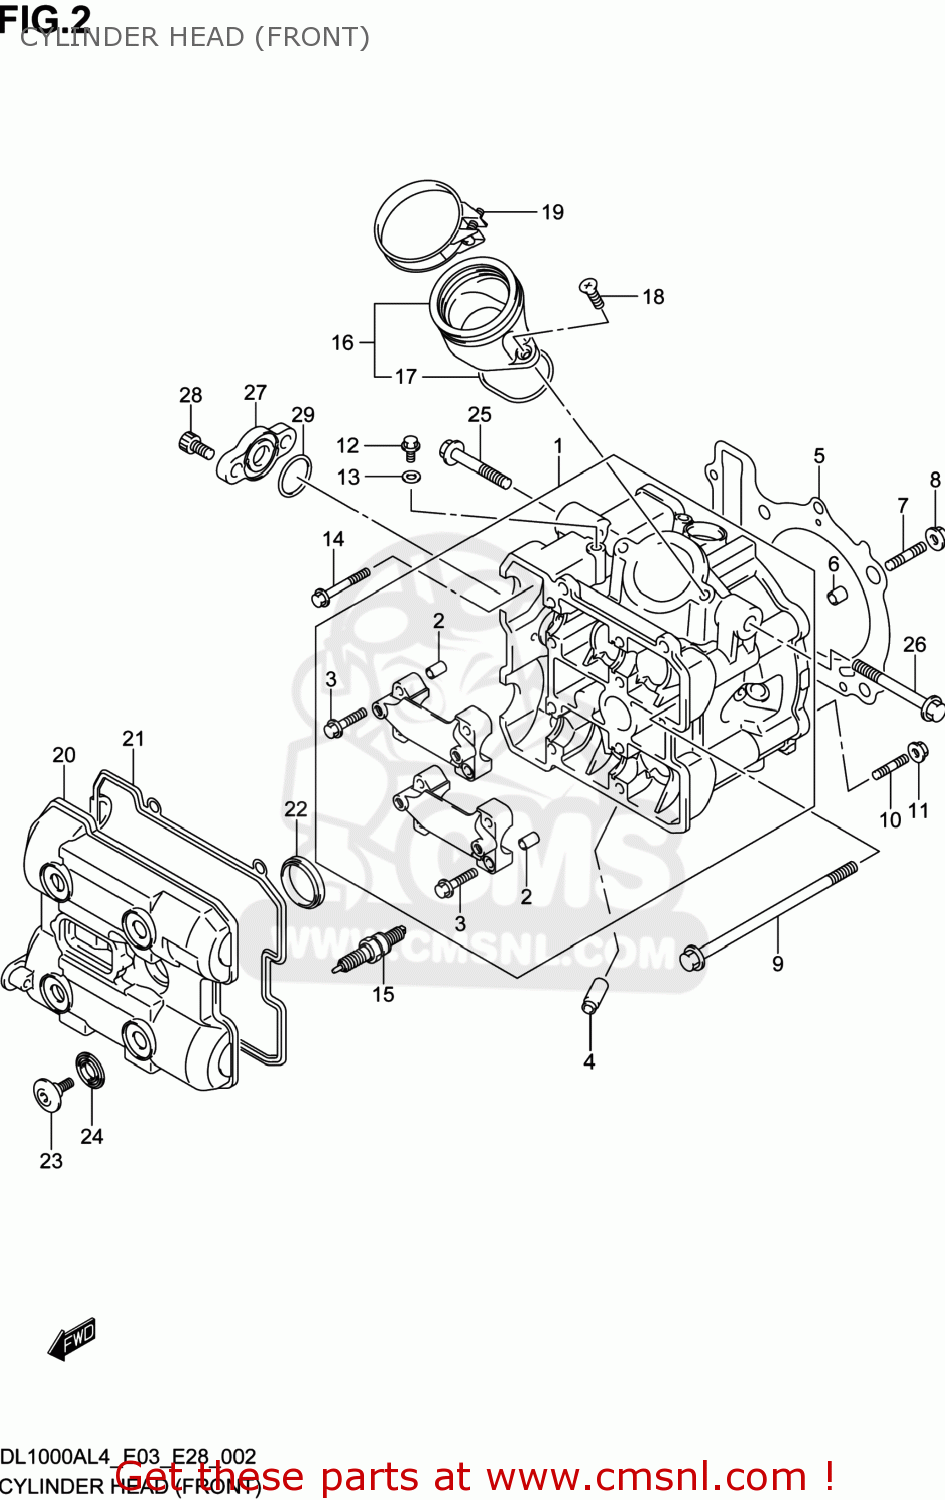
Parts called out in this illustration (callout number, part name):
1	HEAD ASSY,CYLINDER FRONT
2	PIN(6.2X8X11)
3	BOLT(6X40)
4	GUIDE,VALVE
5	GASKET,CYLINDER HEAD (NAS)
6	PIN
7	BOLT,STUD
8	NUT
9	BOLT,CYLINDER HEAD(L:165)
10	BOLT,STUD
11	NUT
12	BOLT(6X12)
13	GASKET(5.8X13X1.2) (NAS)
14	BOLT(6X60)
15	PLUG,SPARK(LMAR8BI-9)
16	PIPE ASSY,INTAKE FRONT
17	O RING(D:2.4,ID:55.6)
18	SCREW
19	CLAMP,INTAKE PIPE
20	COVER,CYLINDER HEAD FRONT
21	GASKET,CYL HEAD COVER NO.1 (NAS)
22	GASKET,CYL HEAD COVER NO.2
23	BOLT(7X17.5)
24	WASHER,CYL HEAD COVER
25	BOLT
26	BOLT
27	COVER,CYL HEAD NO.2
28	BOLT(6X12)
29	O RING(D:2.4,ID:19)
